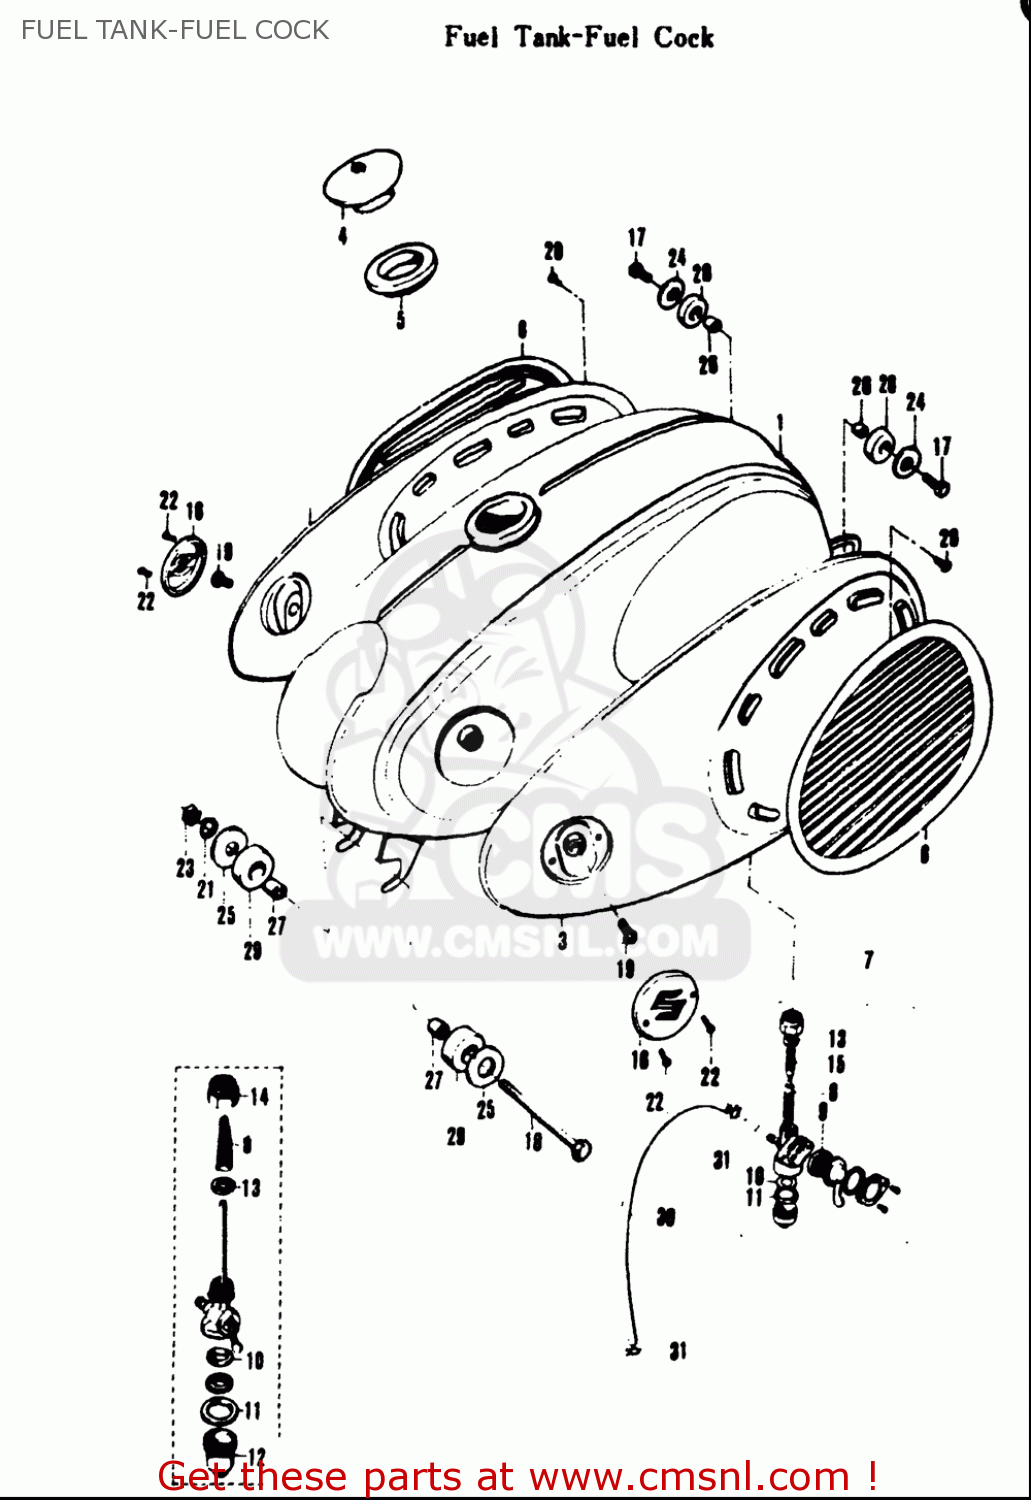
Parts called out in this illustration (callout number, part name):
4	CAP ASSY,FUEL TANK FILLER
7	COCK ASSY,FUEL
9	GASKET,LEVER (NAS)
10	NET,STRAINER
11	GASKET,STRAINER CUP (NAS)
13	GASKET,FUEL COCK (NAS)
20	SCREW(5X6)
21	WASHER,LOCK
24	WASHER(6.5X24X1.6)
25	WASHER(8.5X26X1.6)
26	SPACER(6.5X10X7)
27	SPACER(8.5X12X11)
28	CUSHION
30	HOSE(5X8.2X2000)
